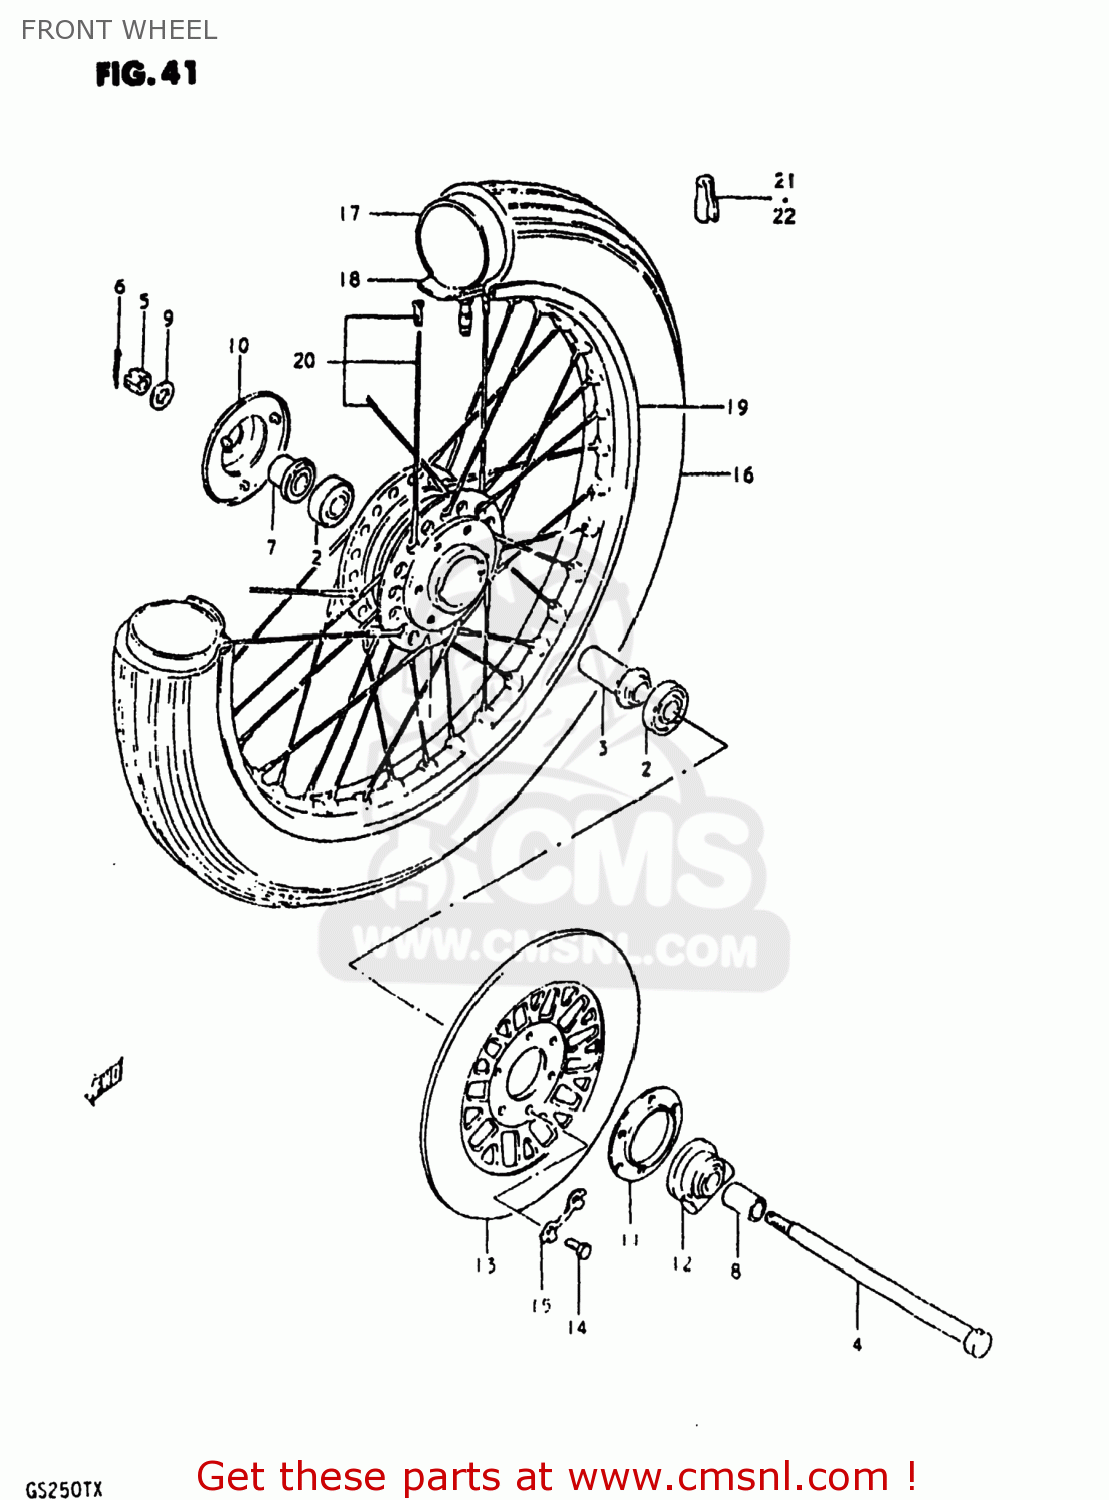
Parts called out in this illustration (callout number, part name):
1	DRUM,FRONT HUB
2	BEARING
3	SPACER,FR HUB BEARING
4	AXLE,FRONT
5	NUT 12MM
6	COTTER PIN
7	SPACER,FR HUB BEARING,R
8	SPACER(15X22X30)
9	WASHER
10	COVER,FR HUB,R
11	DUST SEAL,SPEEDOMETER GEAR BOX
12	BOX ASSY,SPEEDOMETER GEAR
13	DISC,FR BRAKE
14	BOLT(8X25)
15	WASHER
16	TIRE,FRONT
17	TUBE,INNER
18	PROTECTOR,INNER TUBE
19	RIM,FR WHEEL
20	SPOKE SET,FRONT
21	BALANCER,WHEEL (B)
22	BALANCER,WHEEL (30G)
